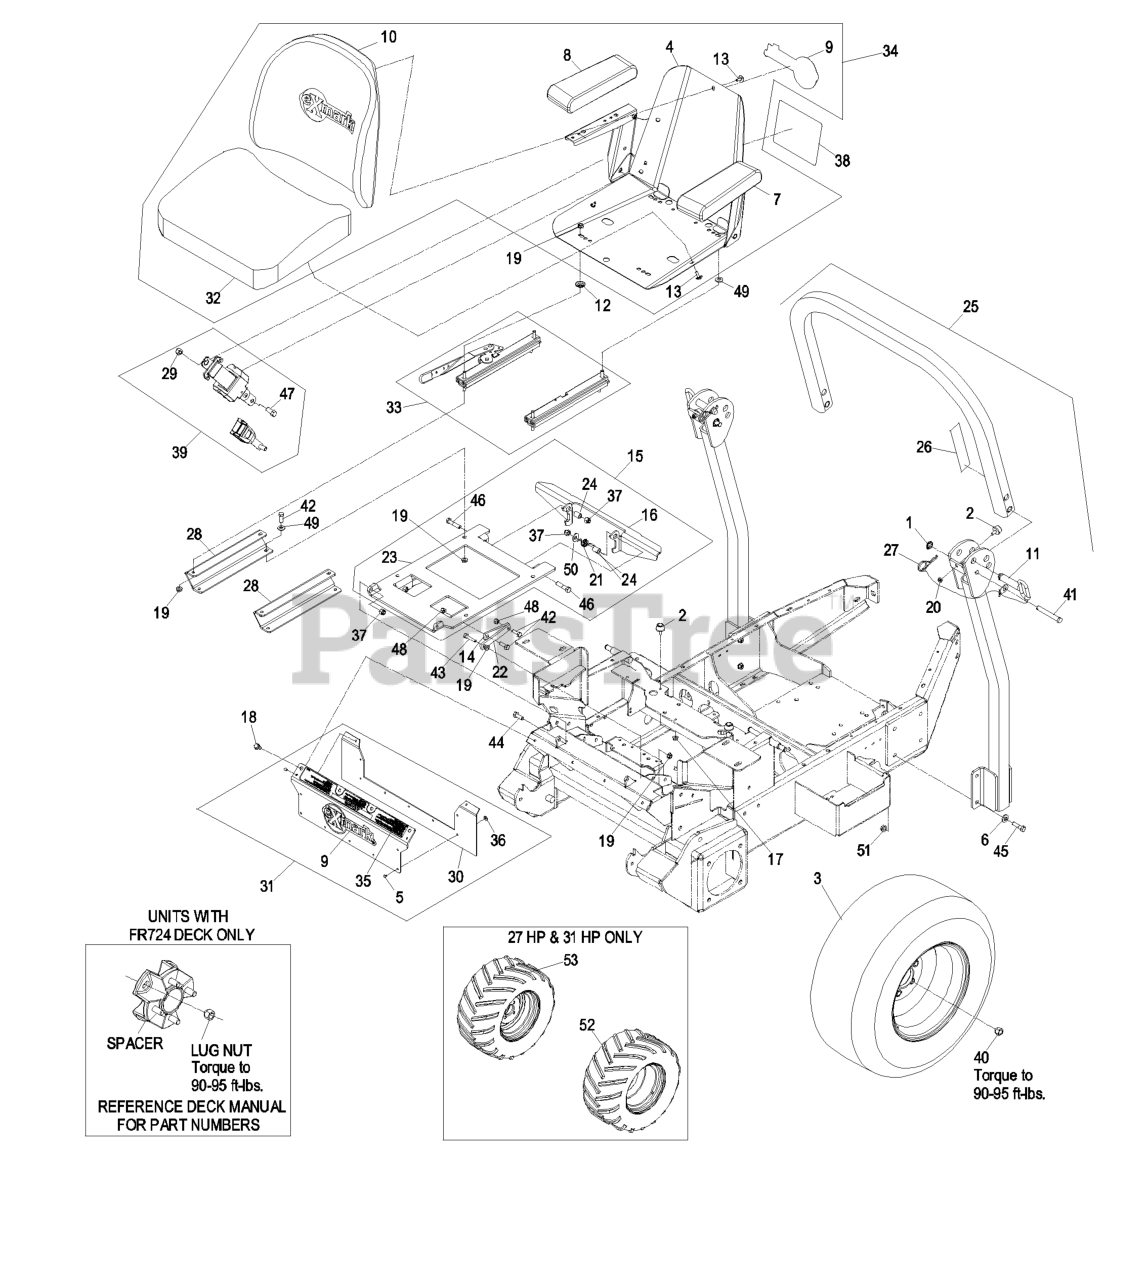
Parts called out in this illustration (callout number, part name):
1	NUT-PUSH
2	BUMPER-RUBBER
3	ASM,WHEEL AND TIRE
4	FRAME-SEAT
5	RIVET-POP
6	WASHER-BELLEVILLE
7	CUSHION,ARMREST LH
8	CUSHION,ARMREST RH
9	DECAL,EXMARK LOGO
10	CUSHION,SEAT BACK
11	PIN-FOLD, ROPS
12	SPACER-TRACK
13	BOLT-SEAT
14	LINK-STOP, SEAT
15	ASM, SEAT FRAME FMZ
18	SCREW-HWH, THREAD CUT
20	NUT-LOCK, NI
22	LINK,FMZ LWR SEAT STOP (P
23	ASM, SEAT FRAME FMZ
24	BUSHING-LEVER, LIFT
25	KIT,ROPS FMZ
26	DECAL-WARNING, FOLDING RO
27	HAIRPIN
28	SUPPORT, ANGLED SEAT
29	NUT-LOCK
30	Skirt, Rubber
31	ASM,FRONT CONSOLE W/ DECA
35	DECAL,TOP CONSOLE
36	WASHER-FLAT
37	NUT-LOCK, NI
38	DECAL,FR SERVICE AID
39	RETRACTABLE SEATBELT KIT
40	NUT-LUG
41	PIN-CLEVIS
42	SCREW-HH
43	SCREW-HH
44	SCREW-HH
45	SCREW-HH
46	SCREW-HH
47	SCREW-HH
48	NUT-LOCK, NI
49	WASHER-FLAT
50	WASHER-FLAT
51	NUT-HHF, WHIZ
52	ASM,WHEEL AND TIRE LUG LH
53	ASM,WHEEL AND TIRE LUG RH
